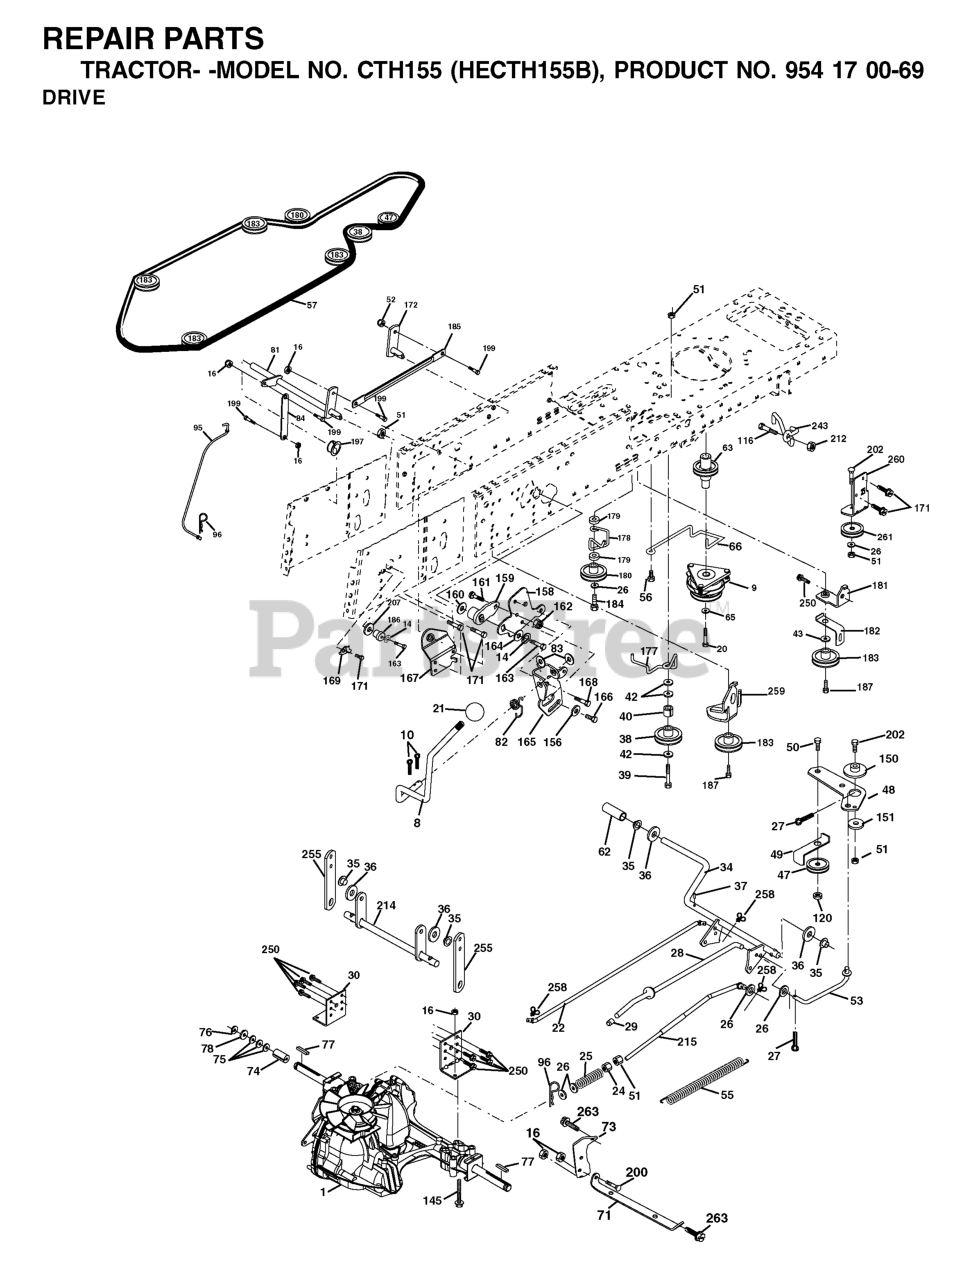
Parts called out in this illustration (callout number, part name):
8	ROD.SHIFT.FENDER.ADJ.LT.CRD
10	PIN COTTER
14	LOCKWASHER
16	NUT.71038.31-18.HEX.NYLOCK
20	BOLT
21	KNOB.DUCKHEAD.1/2
22	ROD
24	NUT
25	SPRING ROD LT
26	WASHER
27	COTTER PIN
28	ROD, PARKING BRAKE
29	PLUNGER CAP
30	BRKT, TRNSXLE MNT 20"
33	RP BOLT 5/16-18 X3/4 ZN/YEL GR
34	SHAFT, FOOT PEDAL
35	BEARING.NYLON
37	DRIVE PIN
38	PULLEY.FLAT
42	WASHER
47	IDLER PULLEY
48	BELLCRANK, CLUTCH
49	RETAIN BELT
50	BOLT
52	LOCKNUT
53	LINK, CLUTCH LT
55	SPRING, RETURN LT
56	SCREW.3/8-16
57	V-BELT 113"
62	COVER, PEDAL (1 2)
63	PULLEY.ENGINE.CVX.LT
65	LOCKWASHER
66	KEEPER BELT ENGINE
71	STRAP TORQUE LH HYDRO
73	STRAP TORQUE RH HYDRO
74	SPACER AXLE
77	SQUARE KEY
81	ASM.CROSS.SHAFT.REAR.CRD.0510
82	SHIFT SPRING
83	WASHER
84	LINK.PNT.TRANSAXLE.0510.CRD
95	LINK
96	RETAINER M
116	BOLT D
120	NUT LOCK FLG 3/8-16 UNC
144	Washer 11/32 x 5/8 x 16 Ga SD
145	BOLT HEX 5/16-18 GR 5
150	BUSHING.BELLCRANK.GRD.DR
151	WASHER 12/32X2X10GA
156	WASHER.SRRTD.5/16
158	BRACKET
159	HUB
160	Washer 29/32 x 1 - 1/4 x 16 Ga.
161	BOLT
162	NUT.CROWNLOCK.1/4
164	Washer 5/8 x .281 x 10 Ga.
165	RP BRACKET
167	BRACKET.SUPT.SHIFT.CRD
168	BOLT.SHOULDER.5/16-18X
169	PLATE.FASTENING.CROSS.SHAFT
172	LINK
174	LOCKWASHER
180	PULLEY.FLAT.IDLER
181	BRACKET
182	BELT GUIDE
184	SCREW.HXWSH.3/8
185	LINK
186	HUB.TAPERED.ROUND.CRD
187	BOLT.5/16-18X1.25
197	NYLINER SNAP 5/8" ID
199	BOLT SHOULDER 5/16-18 UNC
206	WASHER
207	WASHER NYL
212	NUT
214	LEVER
215	ROD
243	BRKT ASM MTNG
250	SCREW 3/8-16X3/4
255	SHAFT
258	CLIP RETAINER
259	BRACKET
261	FLAT IDLER PULLEY
263	SCREW, 3/8-16X3/4
